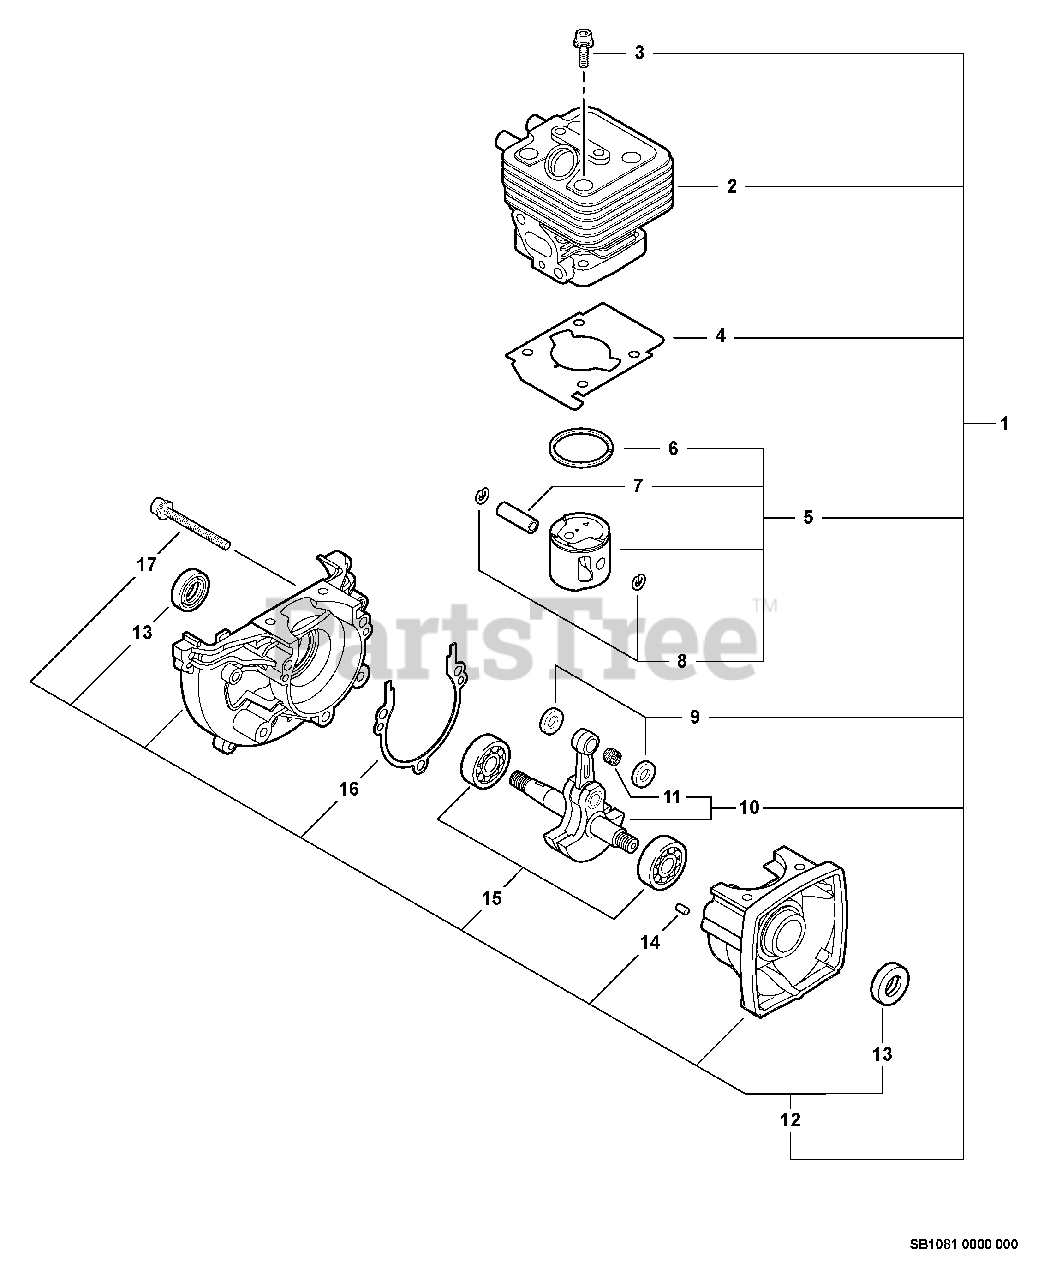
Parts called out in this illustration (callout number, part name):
1	SHORT BLOCK -- SB1081
2	CYLINDER
3	SCREW - 5X25
4	GASKET, CYLINDER
5	PISTON KIT
6	RING, PISTON
7	PIN, PISTON
8	RING, RETAINING
9	SPACER, PISTON
10	CRANKSHAFT ASSY
11	BEARING, NEEDLE - 8
12	CRANKCASE KIT
13	SEAL, OIL
14	PIN - LOCATING
15	BEARING, BALL - 6201
16	GASKET, CRANKCASE
17	SCREW - 5X28
